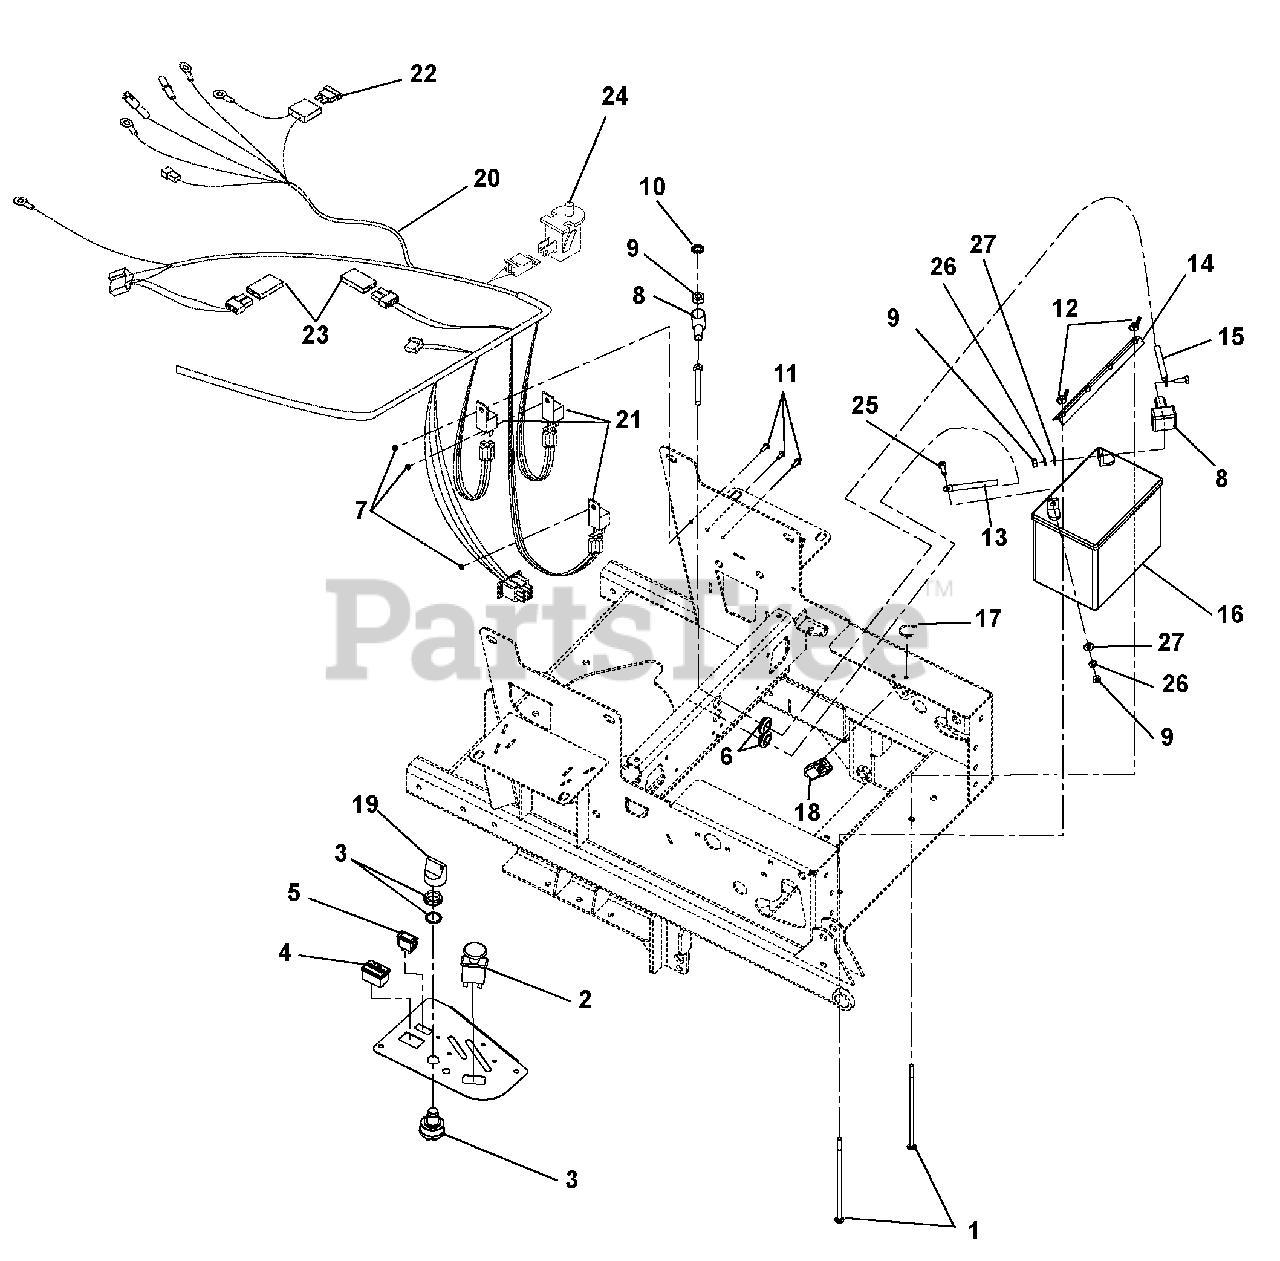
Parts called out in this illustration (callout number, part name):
1	Bolt, Round Head Square Neck .25-20 x 7.50
2	Switch, Clutch
3	Switch, Ignition
4	Hour Meter- Digital
5	Light, Indicator
6	Grommet, Rubber 5/8 ID/1.13
7	Nut, Locking-Nylon 10-24 with Insert
8	Boot, Eyelet Terminal
9	Nut, Hex .25-20
10	Washer, Locking-EXT.262 x .502 x .026
11	Screw, Machine 10-24 x .50 Hex Washer Head
12	Nut, Locking Wing .250-20
13	Ground Cable .31 x 22.00 x .31
14	Hold Down
15	Cable, Positive Battery 26.00"
16	Exide Battery Sealed Maintenance Free U1-250
17	Cable Tie
18	Switch, Snap In- N.O./N.O.
19	Key, with Shield
20	Harness, Wire- IZ, CZ, 100I
21	Relay,Sealed w/Diode
22	Fuse, 30 AMP.
23	Diode, Connector Shell
24	Switch, Snap Mounting (N.O.)
25	Bolt, Hex .25-20 x .75 Grade 5
26	Washer, Locking .25X.062 Regular
27	Washer, Flat-STL.281 x .62 x .065
